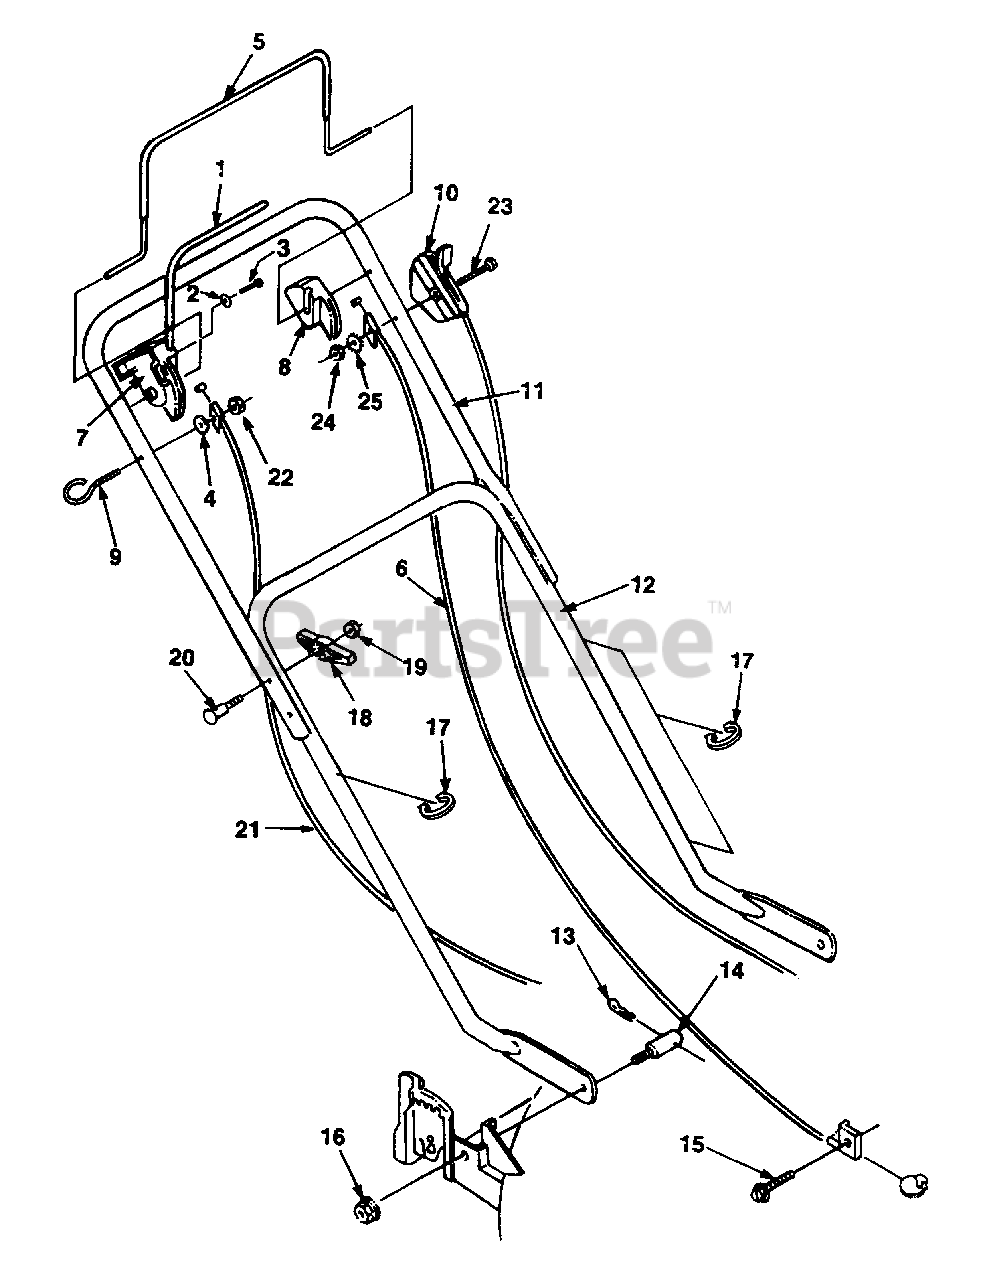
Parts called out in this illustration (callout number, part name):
1	TRACTION LEVER
2	WASHER, Flat, 1/4"
3	SCREW, Hex Hd., 10-16 x 1/2"
4	WASHER
5	BAIL, Brake Control
6	CONTROL, Manual Start
7	ACTUATOR, R.H.
8	ACTUATOR, L.H.
9	EYEBOLT, 1/4-20 x 1-3/4"
10	CONTROL, Throttle
11	HANDLE, Upper
12	HANDLE, Lower
13	PIN, Cotter
15	SCREW, 10-24 x 1 /2"
16	NUT, Flanged, 5/16-18
17	CLAMP, Cable
18	KNOB, Handle
19	NUT, Hex, 5/16-18
20	BOLT
21	CABLE, Traction Control
22	NUT, Hex, 1/4-20
23	BOLT
24	NUT, Hex, 1/4-20
25	WASHER, External Tooth, 1/4"
